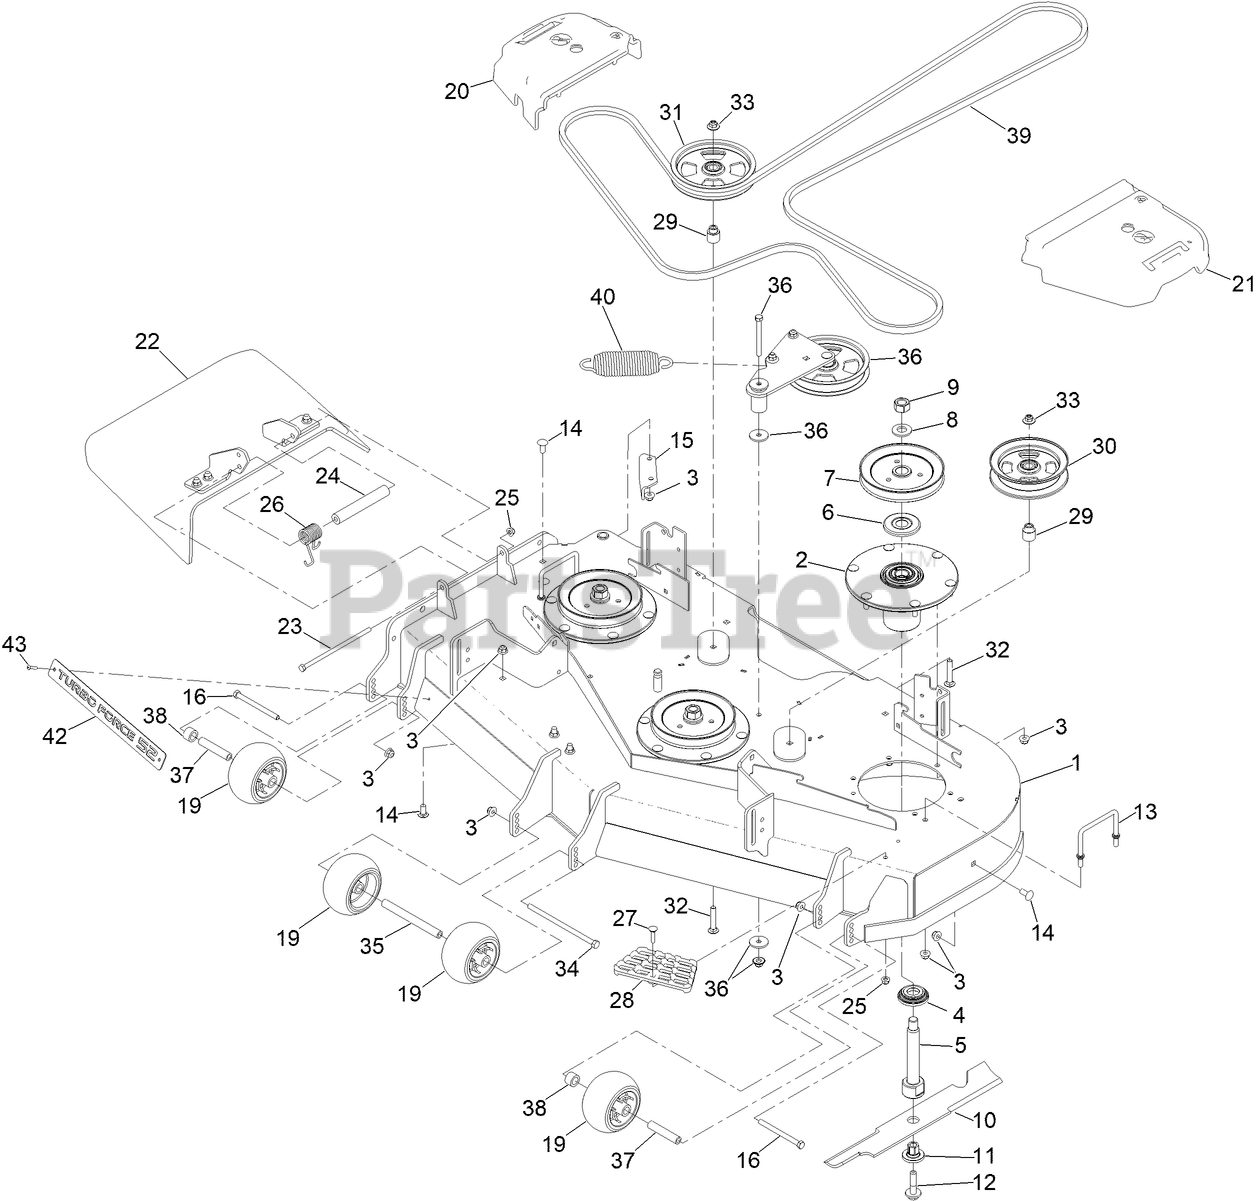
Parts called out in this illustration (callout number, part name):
1	DECK DECAL ASM
2	SPINDLE ASM
3	NUT-HF, NI
4	GUARD-BOTTOM
5	SHAFT-SPINDLE
6	GUARD-BEARING, TOP
7	SHEAVE-BLADE DRIVE 6.50
8	WASHER
9	NUT-HEX
10	BLADE-FLOW, HIGH
11	BUSHING-HEX
12	SCREW-SEMS
13	WIREFORM-COVER
14	SCREW-CARR
15	BAFFLE-DISCHARGE
16	SCREW-HH
19	ROLLER-SCALP, ANTI
20	COVER-BELT, RH
21	COVER-BELT, LH
22	RUBBER DEFLECTOR ASM
23	SCREW-HH
24	SPACER
25	NUT-HF, NI
26	SPRING-TORSION
27	SCREW-CARR
28	STEP-DECK
29	BUSHING, IDLER
30	PULLEY-IDLER, FLAT
31	PULLEY-IDLER, FLAT
32	SCREW-CARR
33	NUT-FLANGE, NI
34	SCREW-HH
35	SPACER-WHEEL
36	IDLER ARM ASM
37	TUBE-SHAFTING
38	TUBE-SPACER
39	BELT-V
40	SPRING-EXTENSION
42	PLATE-TURBO FORCE [BLACK]
43	RIVET-TRIFOLD
